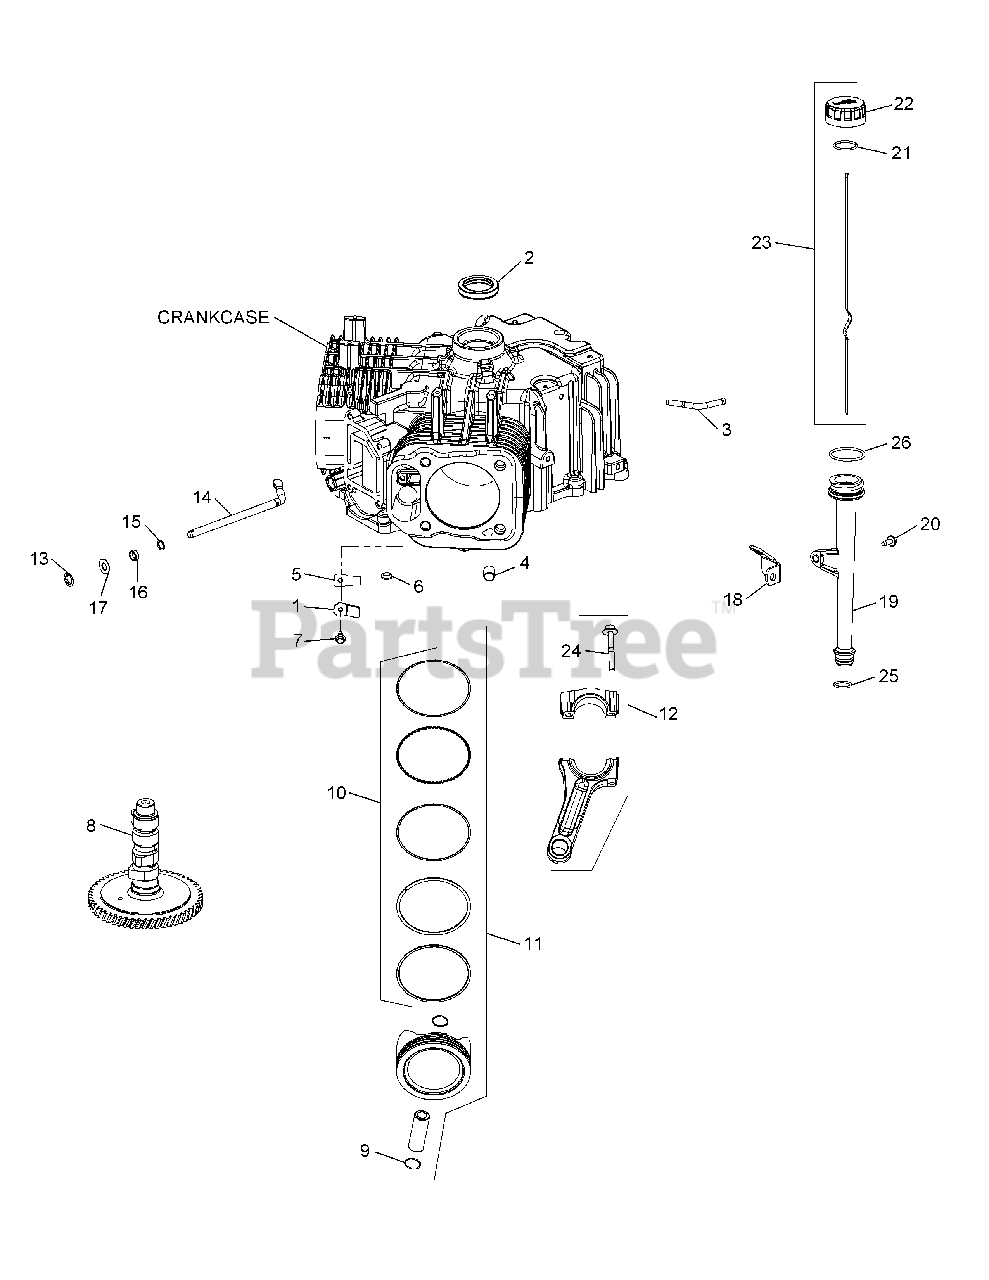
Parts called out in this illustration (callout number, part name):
1	Breather Reed Retainer
5	Breather Reed
7	Flange Screw, M5 x 0.8 x 10
9	Piston Pin Retainer
10	Piston Ring Set (STD)
10	Piston Ring Set (.08)
10	Piston Ring Set (.25)
10	Piston Ring Set (.50)
11	Piston Kit w/ Ring (STD) (Inc. 9 & 10)
11	Piston Kit w/ Ring (.08)
11	Piston Kit w/ Ring (.25)
11	Piston Kit w/ Ring (.50)
12	Connecting Rod Kit (Inc. 24)
13	Ring Retainer
14	Governor Cross Shaft
15	Flat Washer, 11/32"
16	Governor Cross Shaft Seal
17	Flat Washer, 9 mm
18	Oil Fill Tube Bracket
19	Oil Fill Assembly Tube
20	Flange Screw, M5 x 0.8 x 13
21	Dipstick O-Ring
22	Oil Fill Cap Kit (Yellow)
23	Dipstick, Assembly (Inc. 21 & 22)
24	Connecting Rod Bolts Kit
25	Lower Oil Fill Tube O-Ring
26	Upper Oil Fill Tube O-Ring
